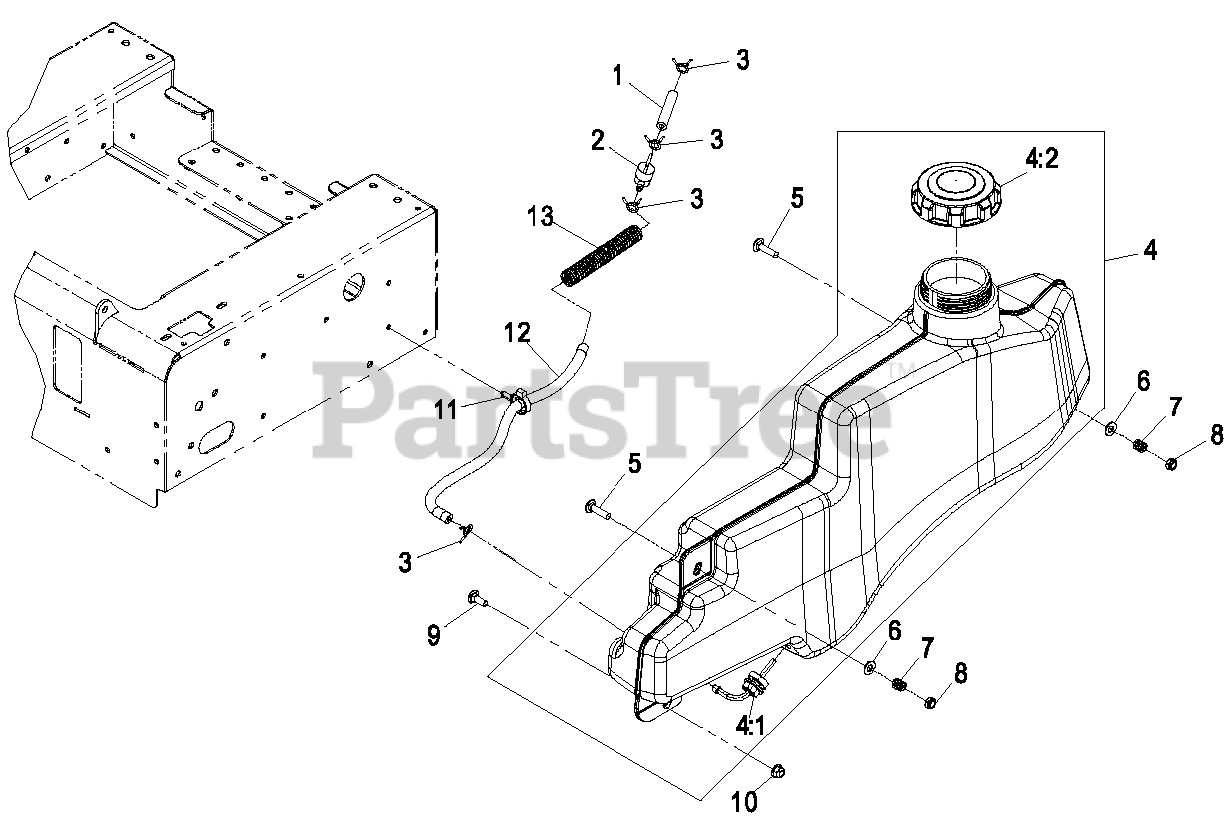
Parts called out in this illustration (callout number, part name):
1	HOSE-FUEL
2	VALVE-FUEL
4	FUEL TANK ASM
4:1	FITTING-FUEL, BULKHEAD
4:2	CAP-FUEL, GAS
5	Bolt-Carriage 5/16-18 X 1 1/4
6	WASHER-PLAIN
7	SPRING-TANK, FUEL
8	NUT-LOCK, NI
9	SCREW-CARR
10	NUT-HF, NI
11	CLAMP-HOSE
12	HOSE-FUEL
13	CONDUIT-FUEL LINE
